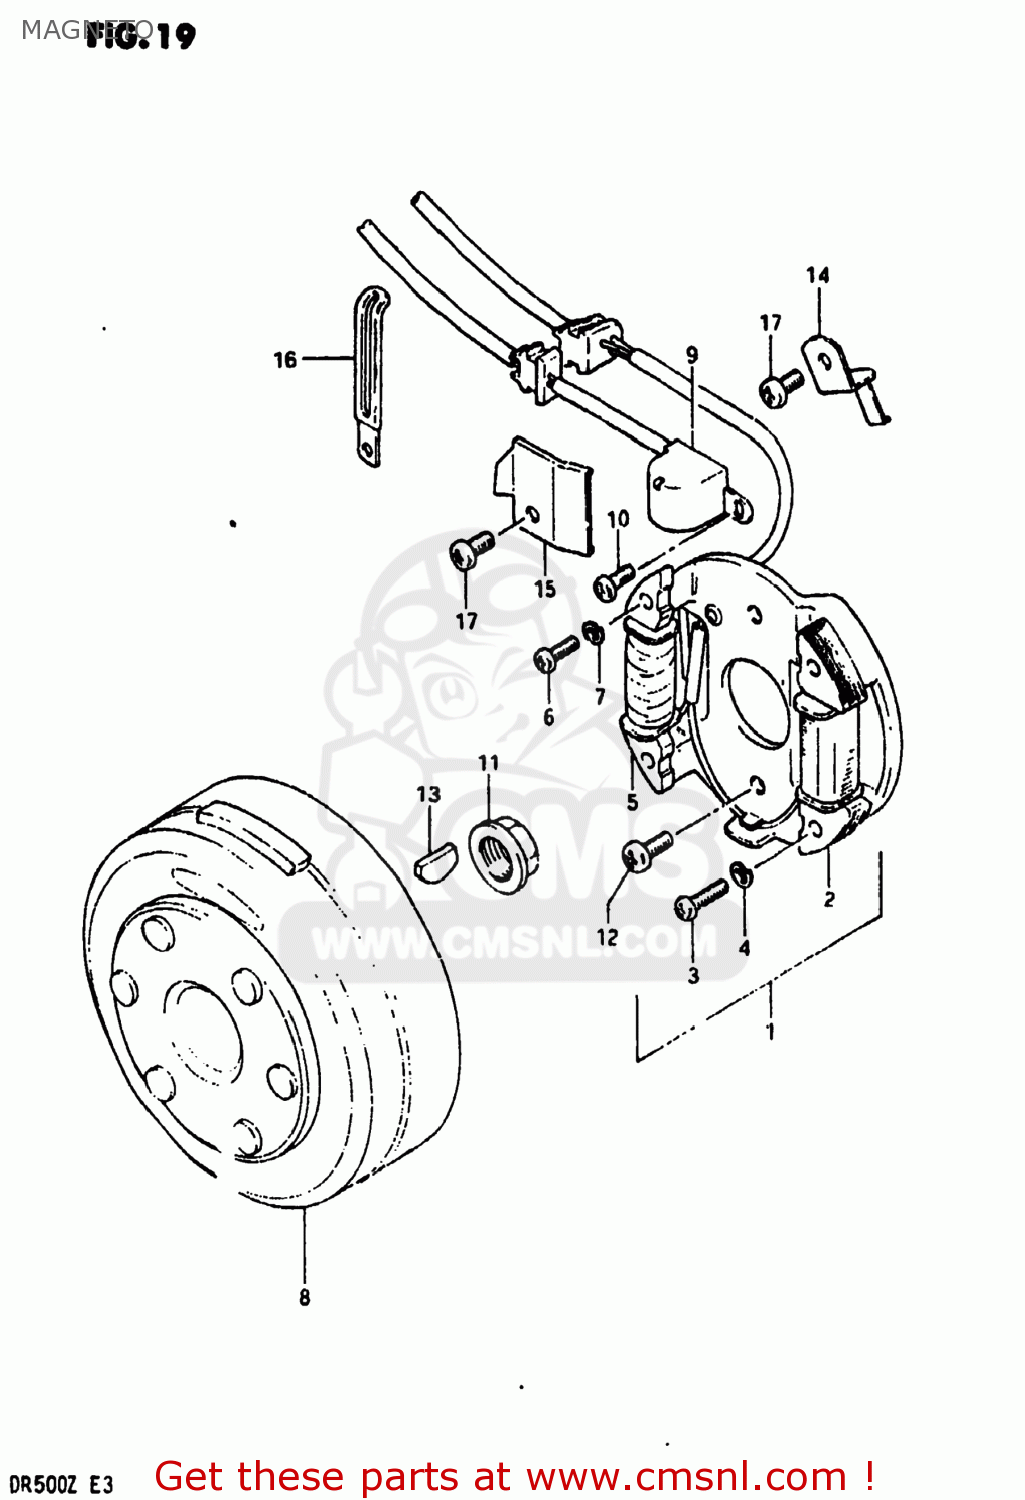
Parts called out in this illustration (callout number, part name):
1	STATOR ASSEMBLY
2	COIL,LIGHTING
3	SCREW 5X20
4	LOCK WASHER
5	COIL,PRIMARY
6	SCREW
7	LOCK WASHER
8	ROTOR,FLYWHEEL
9	COIL ASSY,PICK UP
10	SCREW (SUS)
11	NUT,GENERATOR ROTOR
12	SCREW
13	KEY 4MM
14	CLAMP,MAGNETO LEAD WIRE
15	CLAMP,MAGNETO LEAD WIRE
16	CLAMP
17	SCREW
